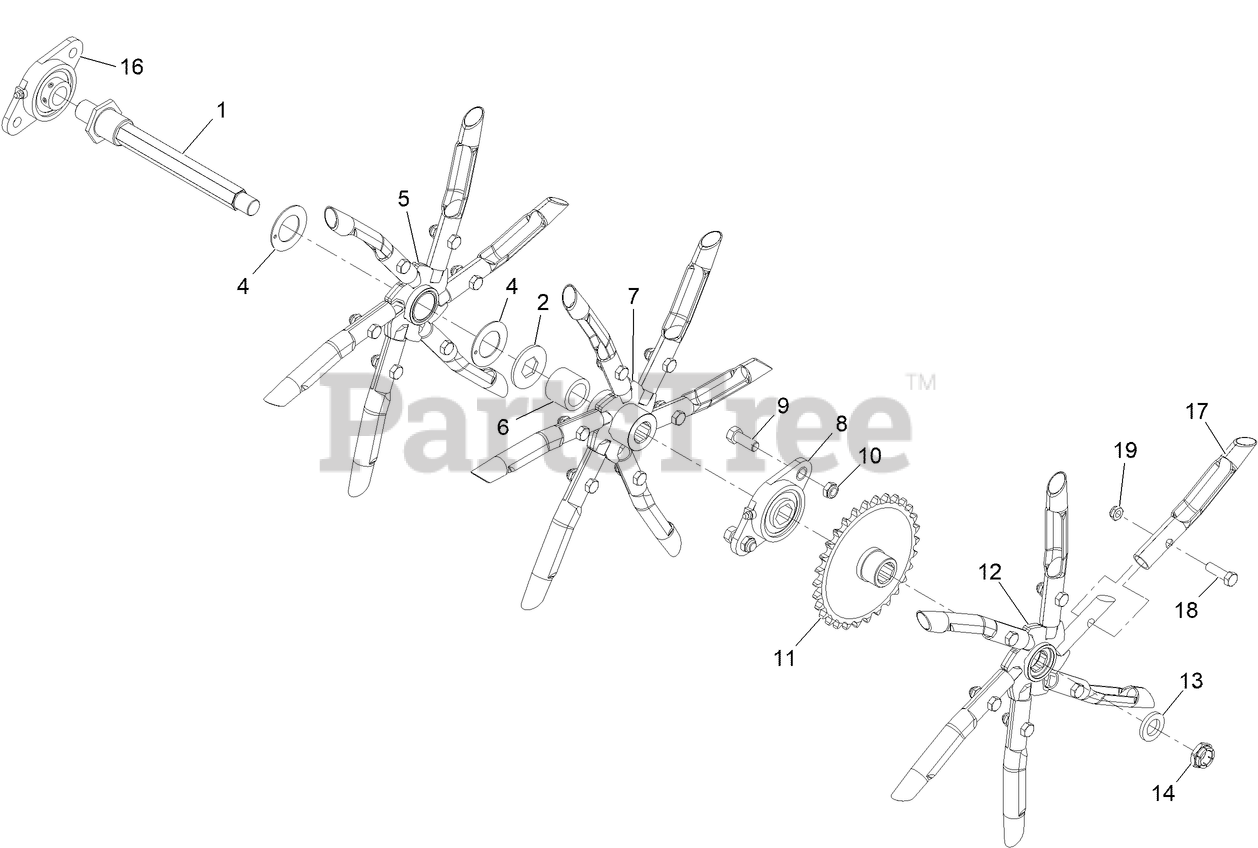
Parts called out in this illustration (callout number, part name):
1	TINE SHAFT ASM
2	KEEPER-TINE, FLOATING
4	WASHER-THRUST
5	FLOATING SPYDER ASM
6	SPACER-TINE
7	DRIVEN SPYDER ASM
8	BEARING-HEX BORE
9	SCREW-HH
10	NUT-LOCK
11	SPROCKET ASM
12	DRIVEN SPYDER ASM
13	WASHER-SPACER
14	NUT-LOCK
16	BEARING-ROUND BORE
17	TINE-CORING (3/4 INCH)
18	SCREW-HH
